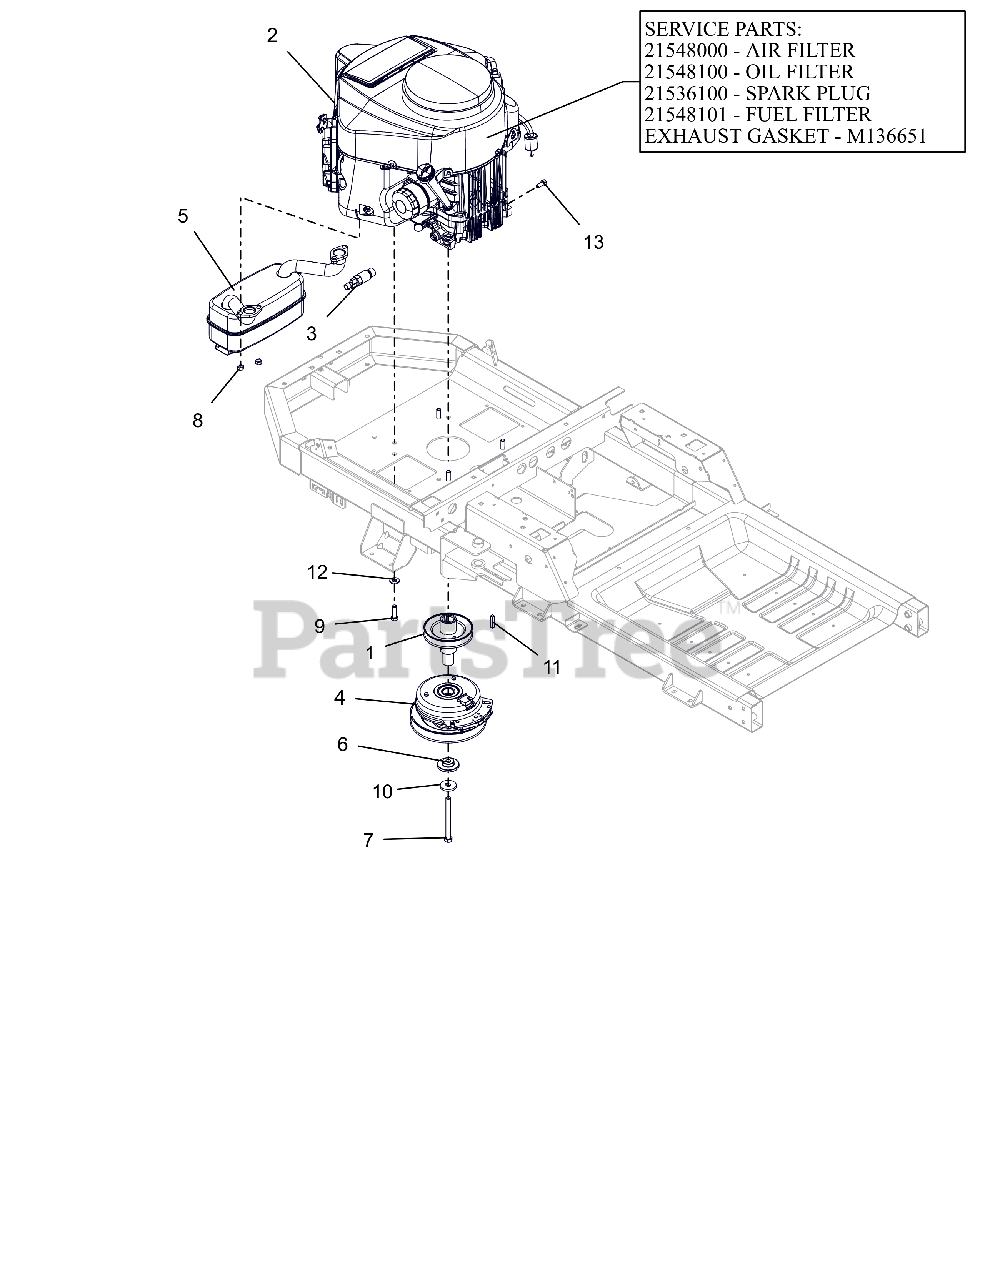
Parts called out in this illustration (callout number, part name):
1	WLDMT, DRIVE SHEAVE-X
2	ENGINE, KAWASAKI FR691 23HP
2	AIR FILTER, KAWASAKI FR
2	OIL FILTER, KAWASAKI FR
2	PLUG, SPARK
2	FUEL FILTER-KAWASAKI FR
2	GASKET, MUFFLER #
3	DRAIN, OIL M20X2.5
4	CLUTCH,105FTLB MONOPOLE 6.83"
5	MUFFLER, KAWASAKI
6	BSHG-FLG .469X1.06X.574X2.0
7	BLT-HEX.438-20X4.5GR8YZ NYTORQ
8	NUT-LK-TOP M8-1.25 YWZC
9	BLT-HEX.38-16X1.25 G5YZ NYTORQ
10	WASHER, 7/16" SPRING DISK
11	KEY-SQ .25 X 1.25 X .25 SAE
12	WASHER, 3/8" SPRING DISC
13	BLT, HEX M8-1.25X20 G8.8 ZCC
